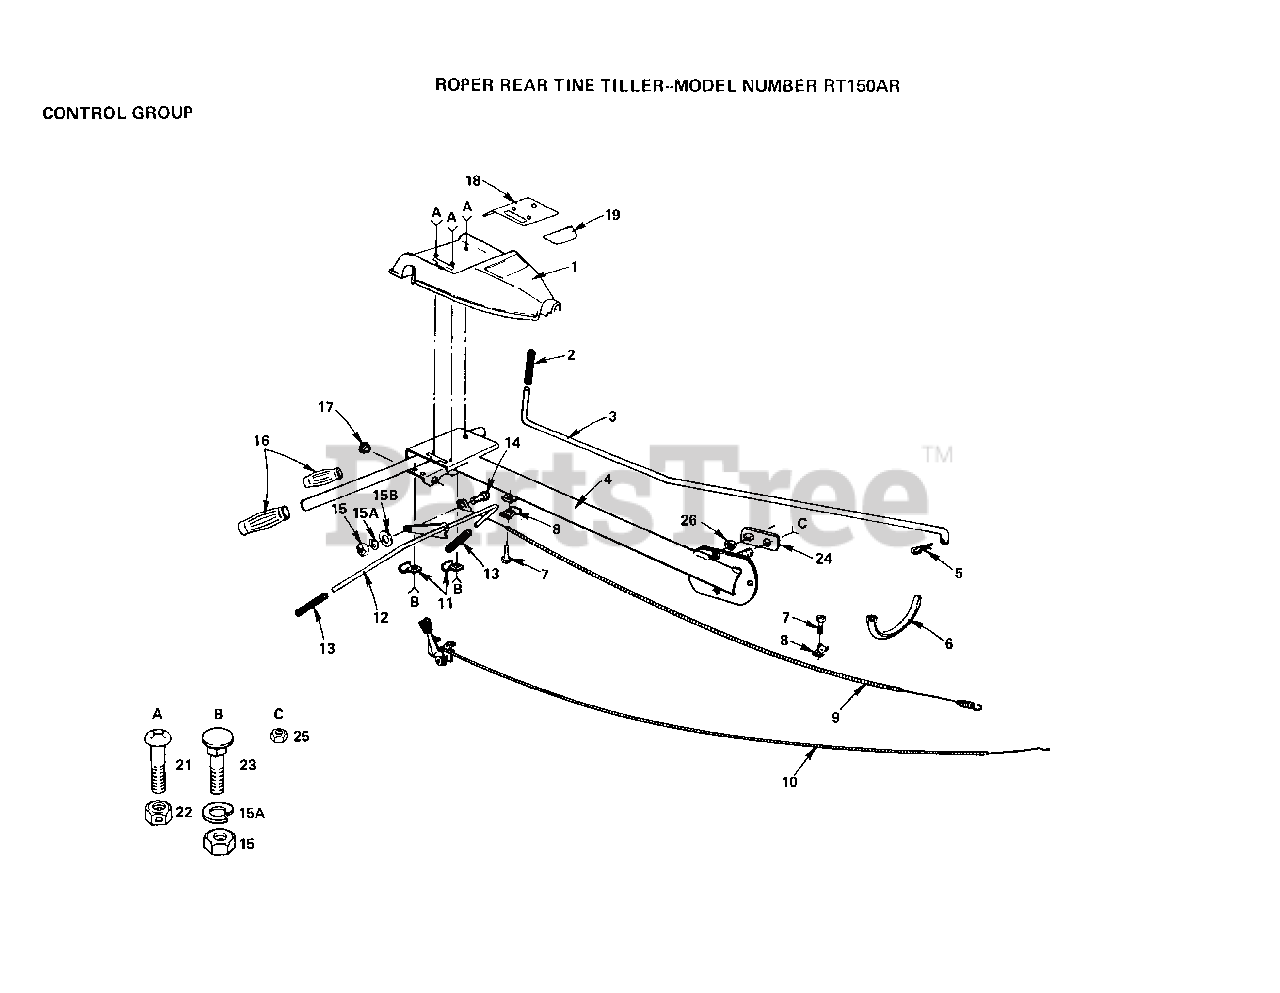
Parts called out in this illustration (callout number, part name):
1	PANEL - CONTROL
2	GRIP TI
5	RETAINER M
6	TIE CABLE CRT
7	SCREW TI
8	CONDIUT CLIP T
9	CABLE.CLUTCH.CRT
10	CTRL-THROTTLE T
13	GRIP BAR CRT
14	SHOULDER BOLT ST
15A	LOCKWASHER
15B	WASHER
17	GROMMET TI
19	DECAL - CONTROL PANEL
23	BOLT
24	"NUT, LOCK CRT"
25	LOCKNUT
26	NUT FLANGE CRT
